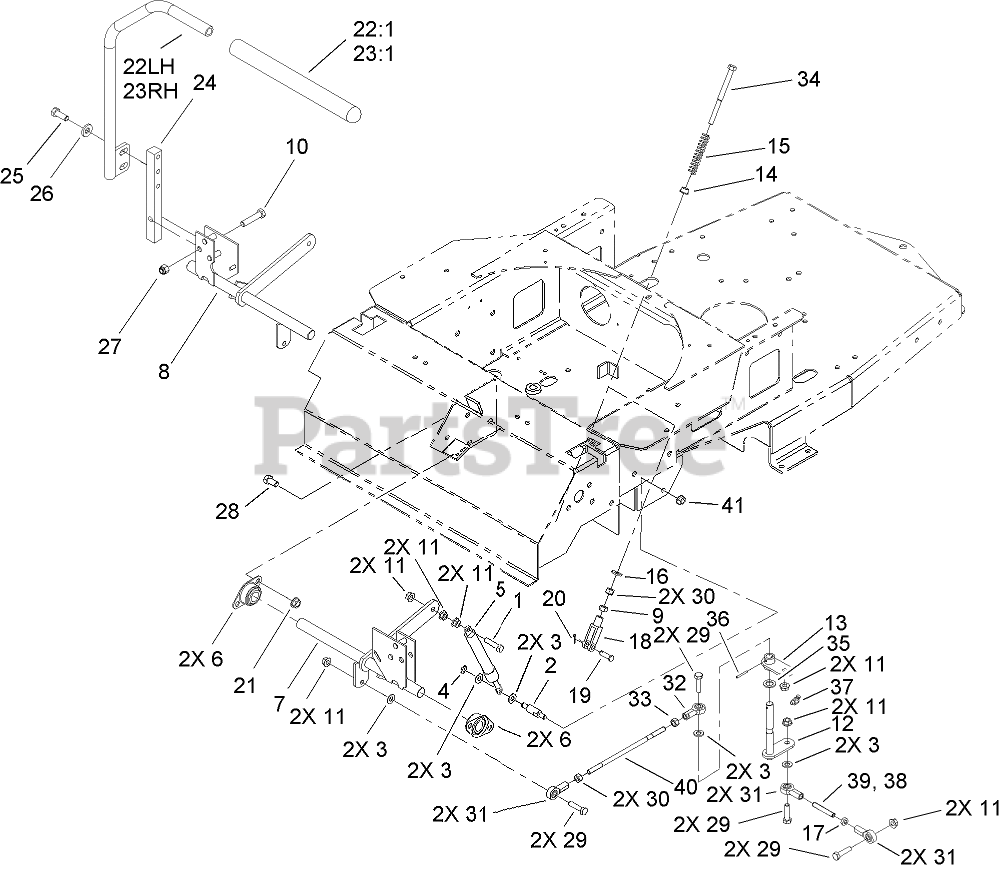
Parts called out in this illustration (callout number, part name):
1	SCREW-HH
2	PIN-DAMPER
3	WASHER-PLAIN
4	RING-RETAINING, EXT
5	Damper-Control, Motion
6	BEARING-FLANGE, SIDE
7	BRACKET-MOTION CONTROL, LH
8	BRACKET-MOTION CONTROL, RH
9	NUT-LOCK
10	SCREW-HH
11	NUT-HF
12	PIVOT ASM
13	PIVOT PLATE ASM
14	BUSHING-FLANGED
15	SPRING-RETURN, NEUTRAL
16	WASHER-FLAT
17	NUT-JAM
18	YOKE-ADJUSTABLE
19	PIN-CLEVIS
20	PIN-COTTER
21	NUT-HHF, WHIZ
23	RH LEVER ASM
23:1	GRIP-CONTROL, MOTION
24	ARM-SHAFT, CONTROL
25	SCREW-HH
26	WASHER-BELLEVILLE
27	NUT-LOCK, NI
28	SCREW-HH
29	SCREW-HH
30	NUT-HEX
31	BALLJOINT-RH
32	BALLJOINT-LH
34	BOLT-RETURN, NEUTRAL
35	WASHER
36	PIN-ROLL
37	FITTING-LUBE, 45 DEG
39	LINKAGE-LOWER, LH
40	LINKAGE-UPPER
41	NUT-HF
